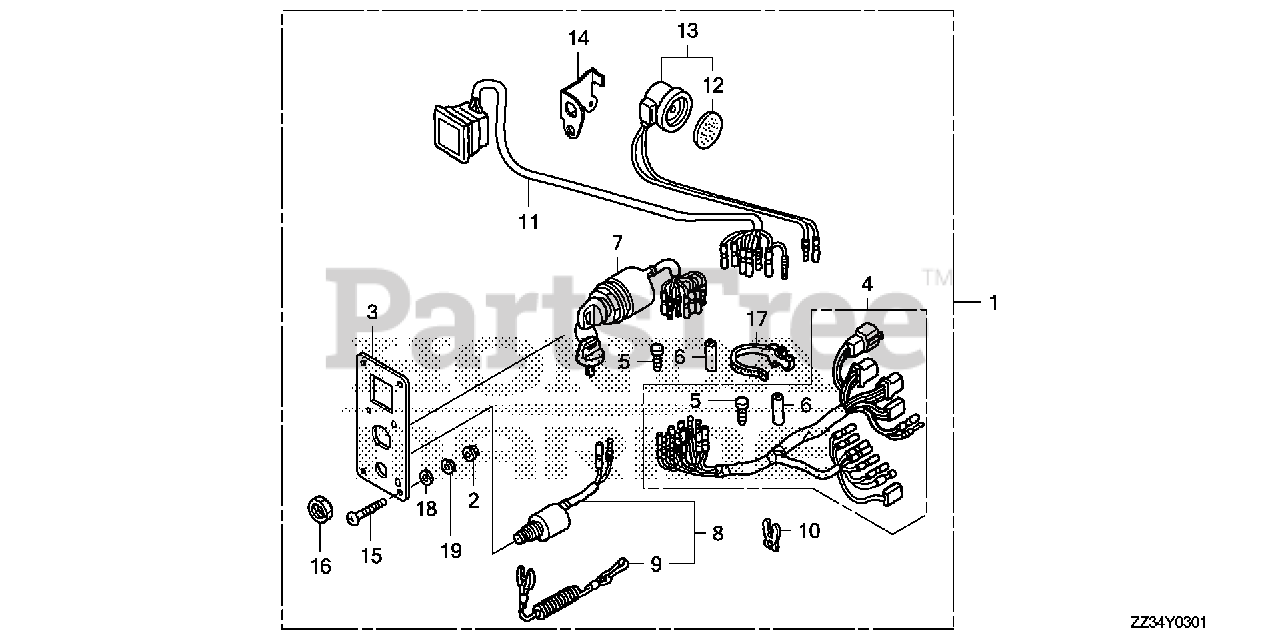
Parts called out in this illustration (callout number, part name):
1	PANEL KIT, SWITCH (4-LED)
2	NUT, FLANGE (5MM)
3	PANEL, CONTROL
4	HARNESS ASSY., SWITCH PANEL
5	PLUG, CONNECTOR (INNER)
6	PLUG, CONNECTOR (OUTER)
7	SWITCH ASSY., COMBINATION
8	SWITCH ASSY., EMERGENCY STOP
9	WIRE, EMERGENCY
10	CLIP, EMERGENCY LOCK
11	LAMP ASSY., INDICATION (4-LED)
12	PLATE, TURN SIGNAL BUZZER
13	BUZZER, WARNING
14	BRACKET, BUZZER
15	SCREW, PAN (5X40)
16	NUT, HEX. (16MM)
17	BAND, WIRE HARNESS (150MM) (NATURAL)
18	WASHER, PLAIN (5MM)
19	WASHER, SPRING (5MM)
